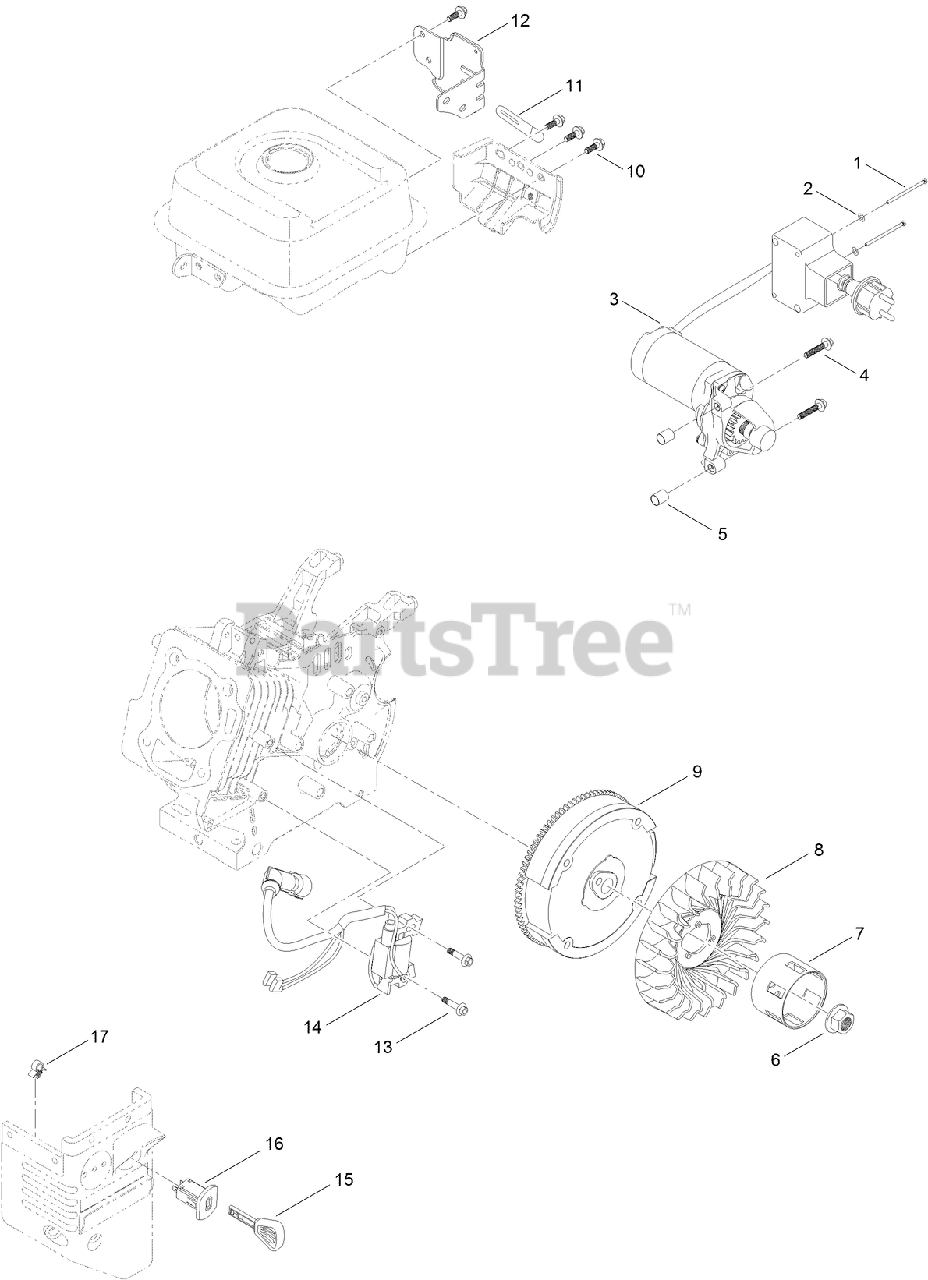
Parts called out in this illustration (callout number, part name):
1	SCREW-BHP
2	WASHER-PLAIN
4	SCREW-FLANGE
5	PIN-DOWEL
6	NUT-FLANGE
7	CUP-STARTER
8	FAN-COOLING
9	FLYWHEEL AND RING GEAR ASM
10	SCREW-HHF
11	CLIP-HARNESS, WIRE
12	BRACKET-SWITCHBOX, STARTER
13	SCREW-HHF
14	IGNITION COIL ASM
16	SWITCH-KEY
